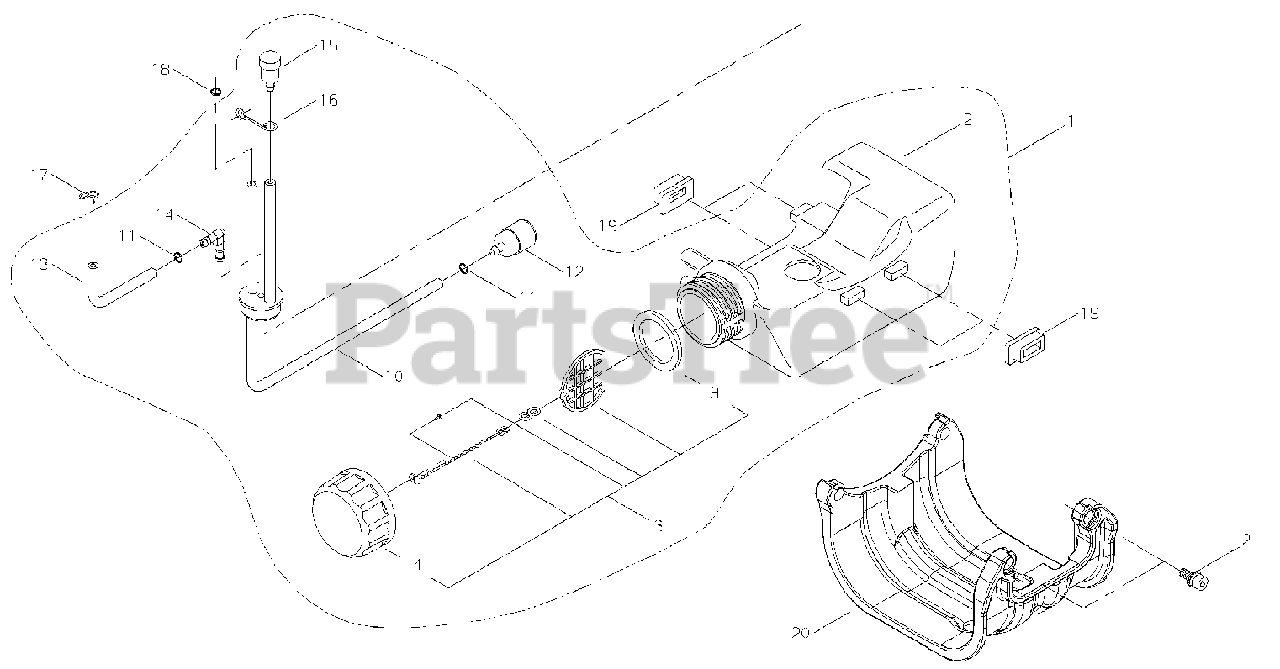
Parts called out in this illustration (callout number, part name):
2	TANK, FUEL
3	CAP ASSY, FUEL
4	CAP, FUEL
9	GASKET, FUEL CAP
10	PIPE, FUEL
11	CLIP Ø6
12	FILTER, FUEL 125-528
13	PIPE, FUEL RETURN
14	CONNECTOR, PIPE
15	VENT ASSY
16	CLIP, VENT ASSY
17	CLIP, SPRING Ø5.2
18	CLIP Ø6
19	CUSHION, FUEL TANK
20	GUARD, PLASTIC FUEL TANK
21	BOLT M5×18
